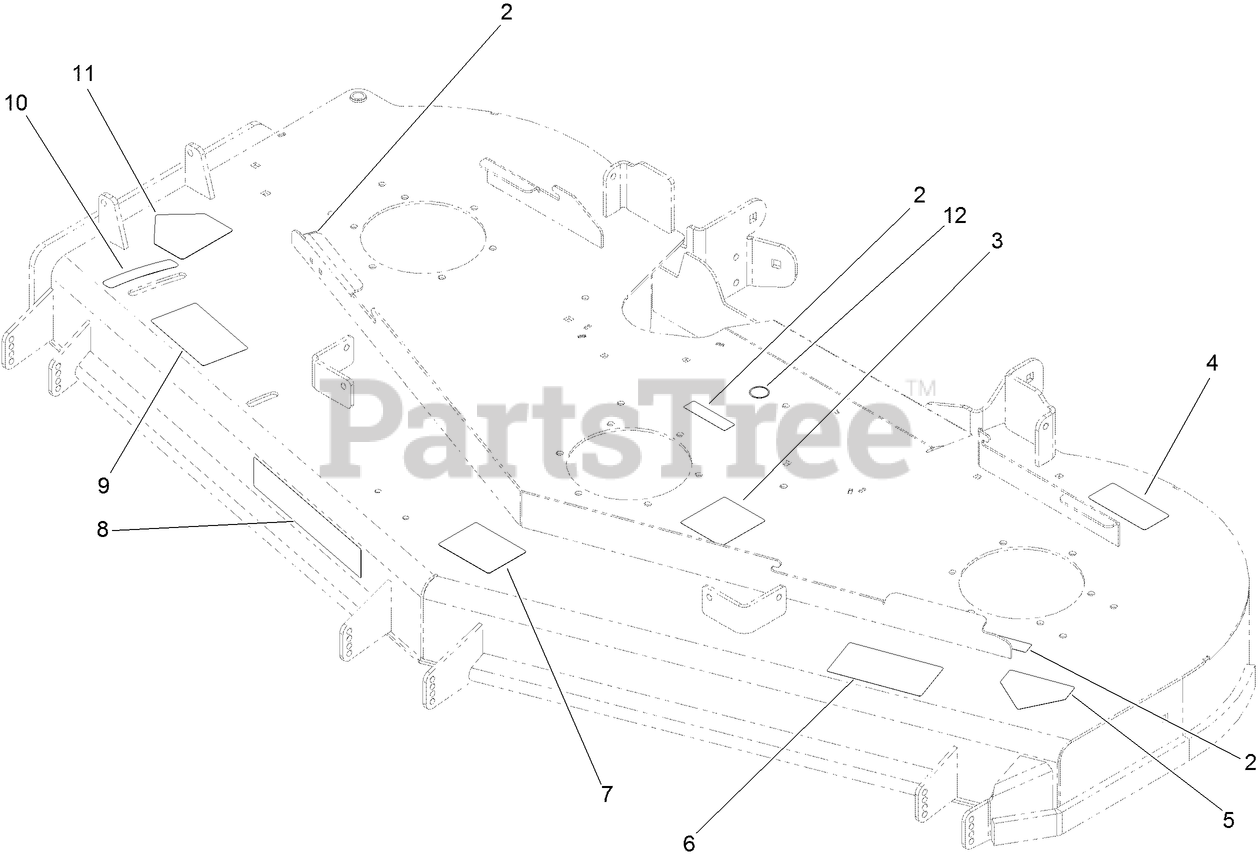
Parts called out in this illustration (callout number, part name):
2	DECAL-COVER, MISSING
3	DECAL-ROUTING, DECK BELT
4	DECAL-TORQUE
5	DECAL-DANGER
6	DECAL-DANGER, THROWN OBJECT
7	DECAL-SCALP, ANTI
9	DECAL-ADJUSTMENT, BAFFLE
10	DECAL-SETTING, BAFFLE
11	DECAL-DANGER
12	DECAL-GREASE
